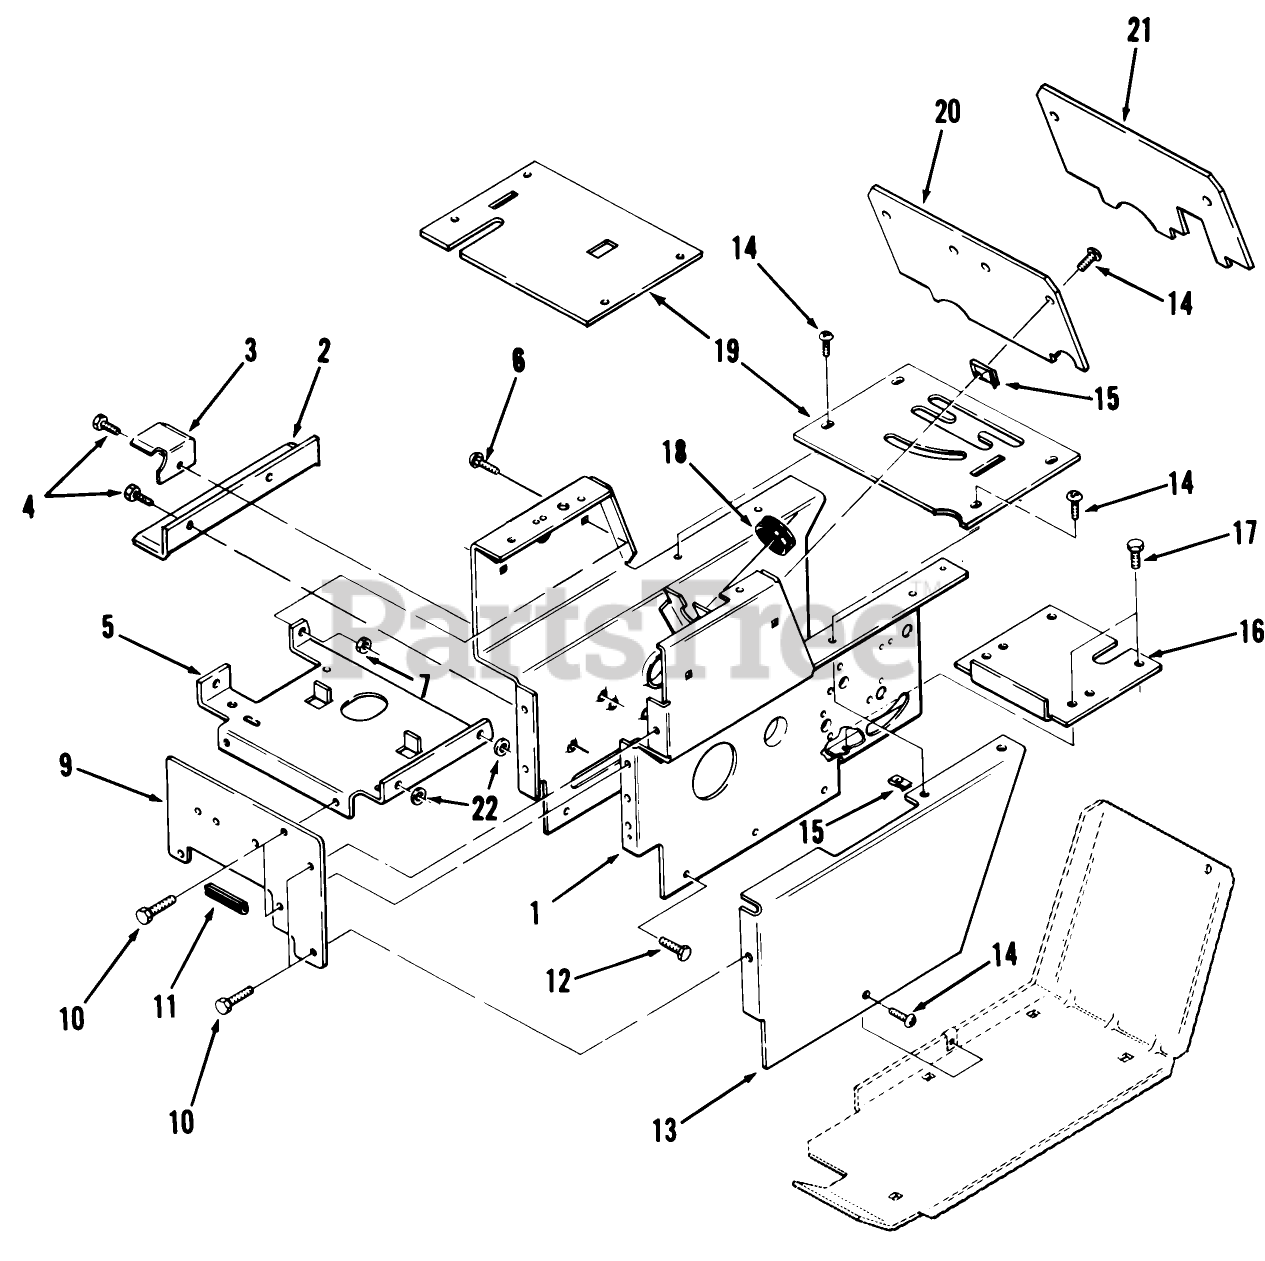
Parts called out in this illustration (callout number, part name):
2	ANGL-BLT GURD*B
3	BRCKET-BLT SUT*B
4	SCREW
6	CARRIAGE BOLT -4
10	SCREW
12	SCREW
17	SCREW
18	GROMMET
